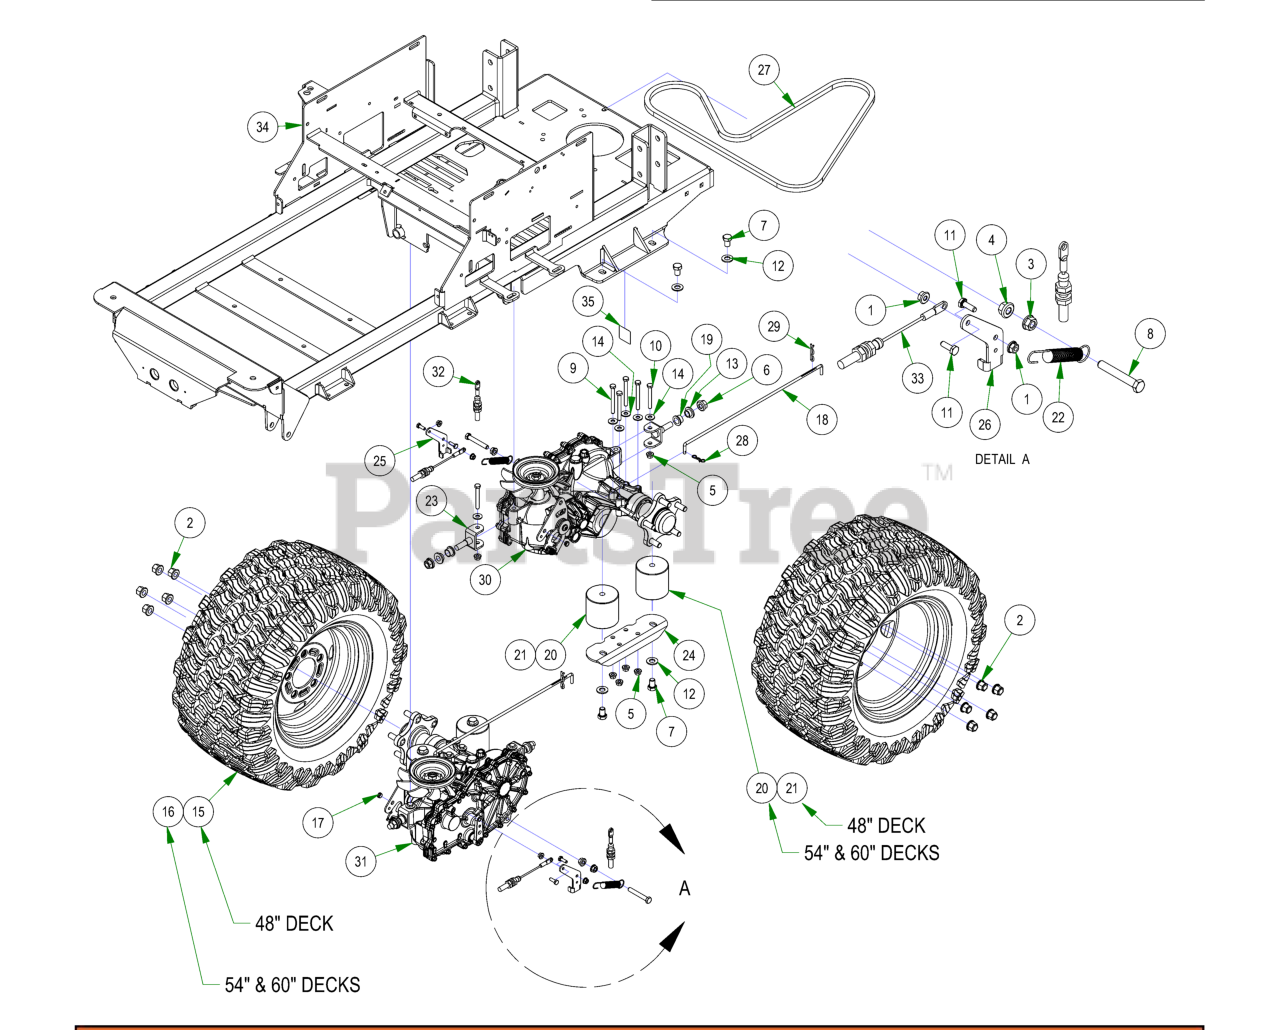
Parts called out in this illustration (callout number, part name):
1	1/4-20 NYL INSERT FLANGE LOCKNUT ZINC
2	Acorn Lug Nut
3	3/8-16 HEX SERRATED FLANGE NUT HARD/ZINC
4	3/8-16 NYLON INSERT FLANGE LOCKNUT (GR.F) ZINC
5	5/16-18 NYLON INSERT FLANGE LOCKNUT ZINC
6	1/2-13 NYLON INSERT FLANGE LOCKNUT ZINC
7	1/2-13 X 3/4 HEX CAP SCREW (GR.5) ZINC
8	3/8-16 X 2-1/2 HEX TAP BOLT (GR.5) ZINC Fully Threaded
9	5/16-18 X 3 HEX CAP SCREW (GR.5) ZINC
10	5/16-18 X 2-1/2 HEX CAP SCREW (GR.5) ZINC
11	1/4-20 X 3/4 HEX CAP SCREW (GR.5) ZINC
12	1/2 SAE FLAT WASHER (1-1/16" OD) GR.8 ZINC YELLOW
13	.525 ID SHOULDER WASHER NYLON
14	5/16 USS FLAT WASHER (7/8 OD) ZINC
15	23x9-12 Reaper Turf Tire & Wheel Assembly
16	23x11-12 Reaper Turf Assembly
17	Drive Arm Transaxle Spacer
18	Neutral Rod
19	.627 ID X .753 OD X .500 LGTH X 1.000 FLG OD X .094 FLG THICK FLANGED BEARING OIL-IMPREG BRNZ
20	Vibration Mount-Green Dot
21	Vibration Mount- Red Dot
22	Brake Return Spring
23	Maverick Rear Transaxle Pivot Bracket
24	Rear Suspension Transaxle Mount
25	Brake Arm Ext (Left)
26	Brake Arm Ext (Right)
27	75.8" Pump Belt
29	Neutral Rod Clip
30	2021 LH 3200 Transaxle
31	2021 RH 3200 Transaxle
32	2021 Load Balanced Brake Cable 1
33	2021 Load Balanced Brake Cable 2
34	2023 Maverick Frame - Painted
35	Patent Decal
